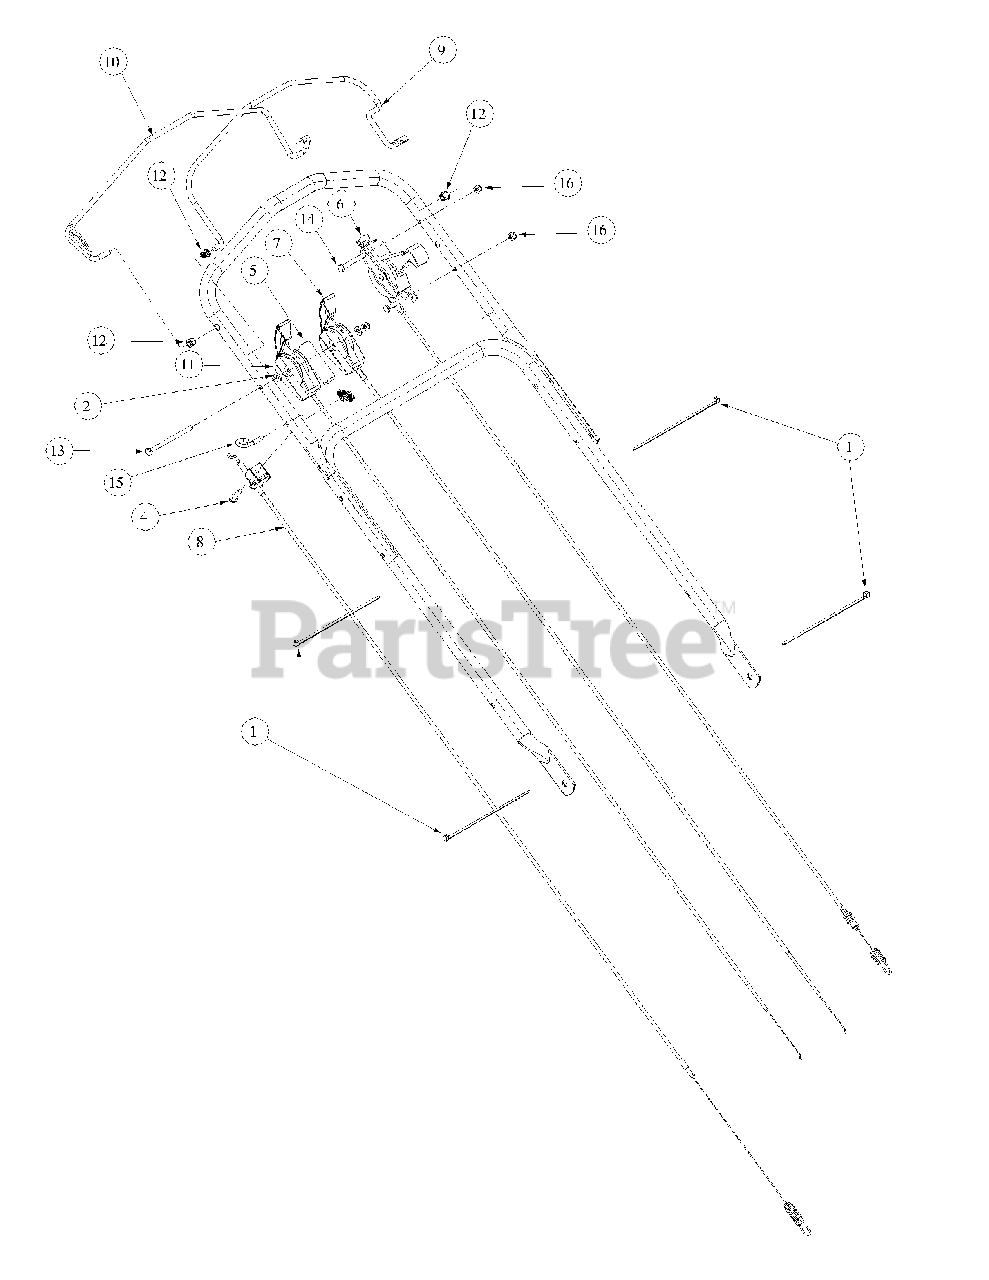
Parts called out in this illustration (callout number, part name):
1	Cable Tie, 3/16 x .05 x 7.4
2	Flatwasher 1/4 x .630 x .0515
3	Hex Head Cap Screw 1/4-20
4	Screw TT 1/4-20, 1.000
5	Spacer, 7/8 DIA x 2.875
6	Control, BBC with Cable
7	Control Shift, 3 Speed w/Cable
8	Cable, Clutch Speed Adjuster
9	Lever Control Bail with BBC
10	Clutch Bail, Transmission, Commutator
11	Control Throttle with Cable
12	Bushing, .3125 Dia Snap
13	Hex Head Cap Screw, 1/4-20, 3.75
14	Hex Head Cap Screw, 1/4-20, 2.50
15	Eye Bolt, 1/4-20, Bent Rope Guide
16	Hex Nut, 1/4-20, Lock
17	Knob, Handle 1/4-20
